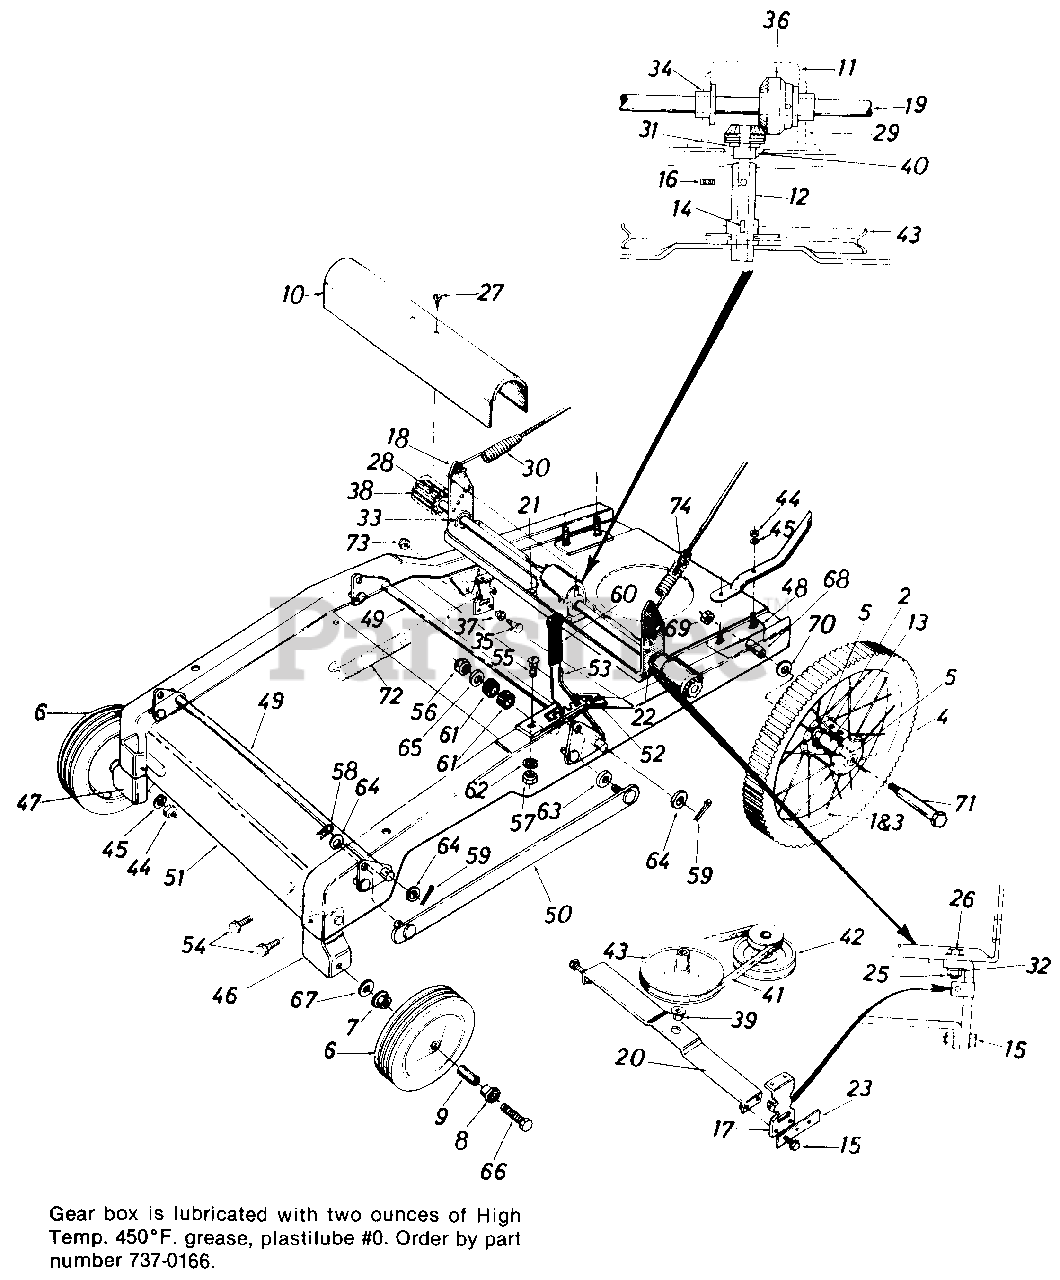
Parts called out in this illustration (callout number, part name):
1	16" Wheel Ass'y. Comp.- Rear
3	Rear Wheel - Rim Only
4	Rear Wheel - Tire Only 16 x 1.75
5	Ball Brg. .630" I.D.
6	Wheel Ass'y. Comp. - Front - 8 x 1.75
7	Flanged Ball Brg. 3/8" I.D.
8	Flanged Ball Brg. 1/2" I.D.
9	Spacer 3/8" I.D.
10	Top Drive Frame Cover
11	Gear Box Cover
12	Pinion Ass'y.
13	Wheel Spacer
14	#2 Woodruff Key 3/32 x 1/2" Dia. Hdn.
15	Hex Sems Bolt 5/16-18 x 1.00" Lg.
16	Set Scr. 5/16-18 x .25" Cup
17	Bottom Drive Frame
18	Top Drive Frame Ass'y.
19	Drive Shaft
20	Bottom Drive Frame Ass'y.
21	Hex Self-Tap Scr. 1/4-20 x .62" Lg.
22	Collar 5/8" I.D.
23	Drive Frame Stop
25	Hex Nut 5/16-18 Thd.
26	Hex Sems Bolt 5/16-18 x .75" Lg.
27	Hex Wash. Hd. AB-Tap Scr. #8 x .50" Lg.
28	Spring Pin Spir. 3/16" Dia. x 1.00" Lg.
29	Gear Box
30	Extension Spring
32	L-Wash. 5/16" I.D.
33	Ball Brg. .630" I.D.
34	Flange Brg. .630" I.D.
35	Shld. Bolt .443" Dia. x .330
36	Bevel Gear .62" I.D. 28 Teeth
37	Pivot Slide
38	Drive Pinion
39	Hex Flange Brg. .503" I.D.
40	Flange Brg. .503" I.D. w/Groove
41	3V-Belt 28" Lg.
42	Double Pulley
43	3/8" V-Pulley .502" I.D. x 6.5" O.D.
44	Hex L-Nut 3/8-16 Thd.
45	L-Wash. 3/8" I.D.
46	Wheel Brk't. Ass'y. - L.H.
47	Wheel Brk't. Ass'y. - R.H.
48	Rear Wheel Brk't. Ass'y.
49	Lift Bracket Shaft Ass'y.
50	Connecting Link Ass'y.
52	Lift Handle Support Brk't.
53	Lift Handle
54	Hex Sems Bolt 5/16-18 x .75" Lg.
55	Carriage Bolt 5/16-18 x .62" Lg.
56	Hex Ins. L-Nut 3/8-24 Thd.
57	Hex Nut 5/16-18 Thd.
58	Intern. Cot. Pin 5/16" Dia.
59	Cot. Pin 1/8" Dia. x 1.00" Lg.
60	Grip - Black
61	Rubber Wash. .33" I.D. x .87" O.D.
62	L-Wash. 5/16" I.D.
63	Fl-Wash. .406" I.D. x 1.25" O.D. x .164
64	Fl-Wash. .510" I.D. x 1.0" O.D. x .060
65	Fl-Wash. .385" I.D. x .87" O.D. x .06
66	Hex Bolt 3/8-16 x 2.00" Lg.
67	Bell-Wash. .400" I.D. x .88" O.D.
68	Spacer .523" I.D. x .640" O.D. x 1.955
69	Hex Top L-Nut 3/8-16 Thd.
70	Fl-Wash. .531" I.D. x .93" O.D.
71	Shld. Bolt .498" Dia. x 4.755
72	Extension Spring .56" O.D. x 8.25" Lg.
73	Hex Ins. L-Nut 5/16-18 Thd.
74	Hex Ins. L-Nut 1/4-20 Thd.
